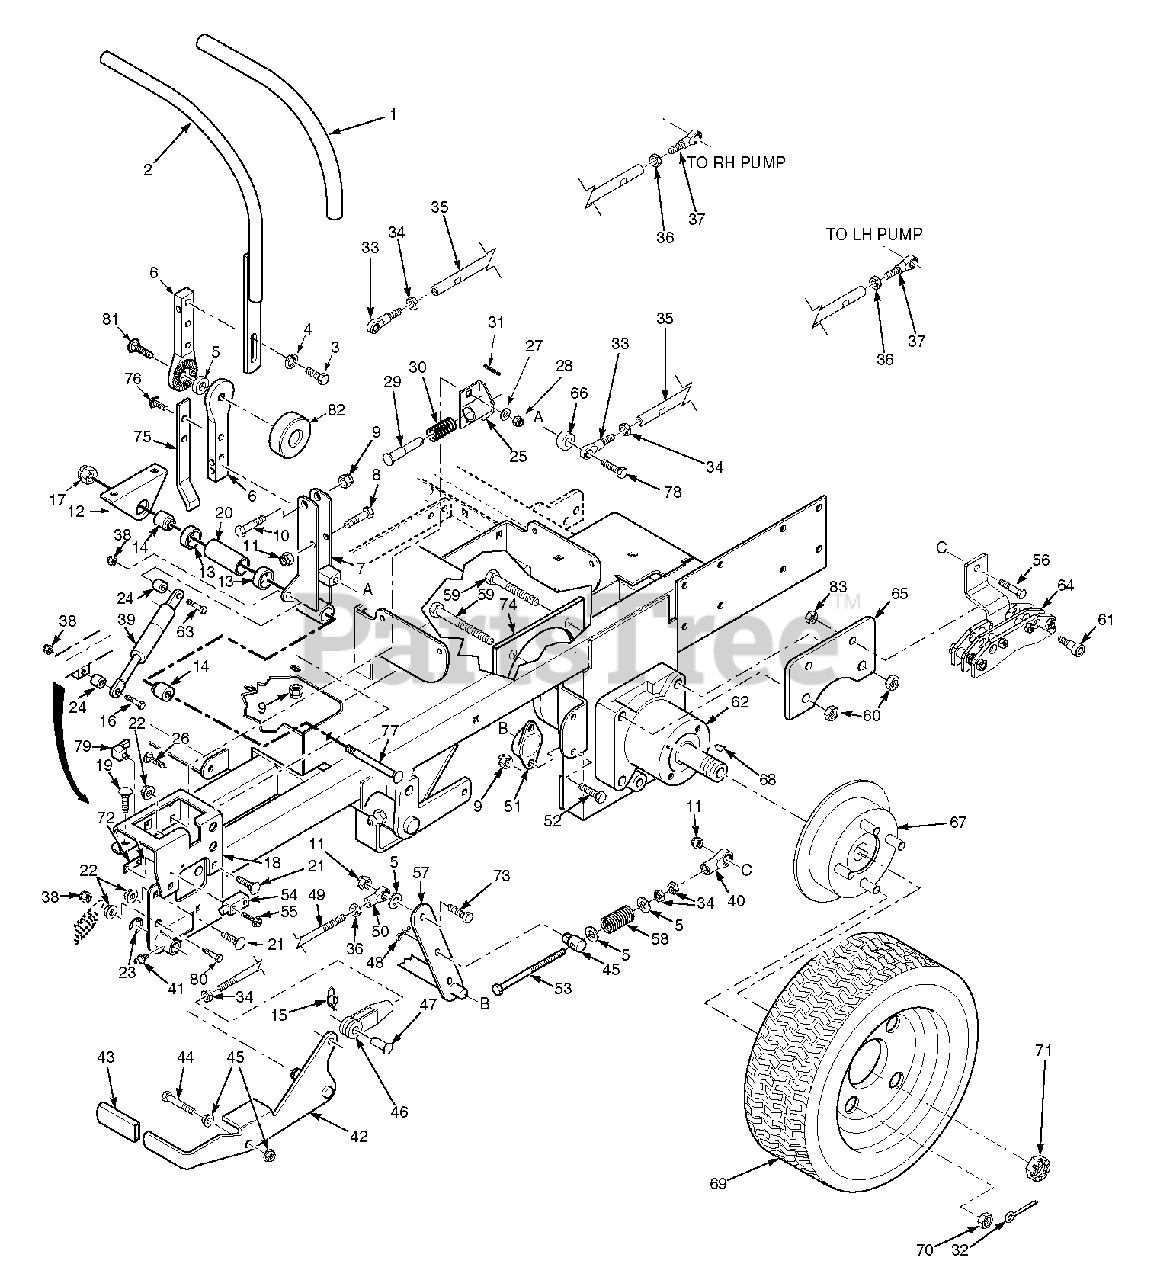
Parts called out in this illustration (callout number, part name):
1	Grip, Handle Bar
2	Handle Bar, LH
2	Handle Bar, RH
3	Bolt, Hex Hd. 5/16-18 x 1"
4	Lockwasher, 5/16"
5	Rubber Spacer
6	Bar, Control Lever
7	Control Lever Weldment, LH
7	Control Lever Weldment, RH
8	Bolt, Hex Hd. 5/16-18 x 2"
9	Nut, Hex Elastic Stop 5/16-18
10	Bolt, Hex Hd. 3/8-16 x 2"
11	Nut, Hex Elastic Stop
12	Mount, Control Linkage
13	Ball Bearings, Neutral Return
14	Spacer
15	Pin, Rue Cotter 3/8" Dia.
16	Bolt, Hex Hd., 5/16-18 x 2.75 Zinc
17	Nut, Hex Elastic Stop 5/8-11
18	Bracket, Control Lever LH
18	Bracket, Control Lever RH
19	Bolt, Carriage 5/16-18 x 1"
20	Spacer, Bearing
21	Bolt, Carriage 5/16-18 x 3/4"
22	Nut, Hex Serr. Flng. 5/16-18
23	Ring, Retaining 5/8" External "E"
24	Spacer
25	Bracket, Neutral Return
26	Bolt, Carriage 1/4-20 x 3/4"
27	Flatwasher, 1/4" (.312 x .750 x .065")
28	Nut, Hex Elastic Stop 1/4-20
29	Pin, Retaining Spring
30	Spring
31	Roll Pin, Spring 5/32 x 3/4"
32	Pin, Cotter 9/16 x 1-1/2"
33	Rod End, Male 3/8-24 RH Thread
34	Nut, 3/8-24 RH Thread
35	Tube, Control Link Liquid-Cooled Engine
36	Nut, Hex 3/8-24 LH Thread
37	Rod End, Male 3/8-24 LH Thread
38	Locknut, 5/16-18, Elastic Stop
39	Gas Damper
40	Rod End, 3/8-24 RH Female
41	Grease Fitting
42	Lever, Parking Brake
43	Grip, Parking Brake
44	Bolt, Hex Hd. 3/8-16 x 2-3/4"
45	Swivel Joint
46	Clevis, Traction Control
47	Pin, Clevis 3/8-16 x 1-1/16"
48	Hair Pin Cotter
49	Rod, Parking Brake
50	Rod End, LH Thread
51	Bushing, Self Align
52	Bolt, Hex Hd. 5/16-18 x 3/4"
53	Bolt, Hex Hd 3/8-24 x 5-1/2"
54	Switch
55	Screw, Hex Sltd. Wshr. Hd. #10 32 x 3/4"
56	Brake Linkage, LH
56	Brake Linkage, RH
57	Bellcrank, Brake Actuator
58	Spring
59	Bolt, Hex Hd. 1/2-13 x 2-3/4" (upper)
59	Bolt, Hex Hd. 1/2-13 x 2-1/2" (lower)
60	Locknut, Hex 1/2-13 Center Lock
61	Bolt, Shoulder 3/8-16 x 2-1/2"
62	Wheel Motor, Hydro-Gear 18E
63	Bolt, Hex Hd., 5/16-18 x 1.75", Zinc
64	Brake Caliper
65	Mounting Bracket, Brake
66	Spacer
67	Wheel Hub/Disk Brake Assembly
68	Key, Woodruff 5/16 x 1"
69	Wheel Assembly 24 x 12-12 Turf Master
69	Rim w/Valve Stem
69	Tire, 24 x 12-12 Turf Master
70	Lug Nut, 1/2-20
71	Nut, Hex Castle
72	Threaded Plate
73	Bolt, Hex Hd. 3/8-16 x 1-1/2"
74	Plate Weldment, Motor Backing
75	Actuator Switch
76	Bolt, Hex Serr. Flng. 5/16-18 x 3/4"
77	Bolt, Carriage 3/8-16 x 4-3/4"
78	Bolt, Hex Hd. 3/8-16 x 1"
79	Switch
80	Bolt, Hex Hd. 3/8-16 x 1-1/4" Grd. 8
81	Bolt, Carriage 5/16-18 x 1-1/2"
83	Nut, Center Lock 3/8-16
